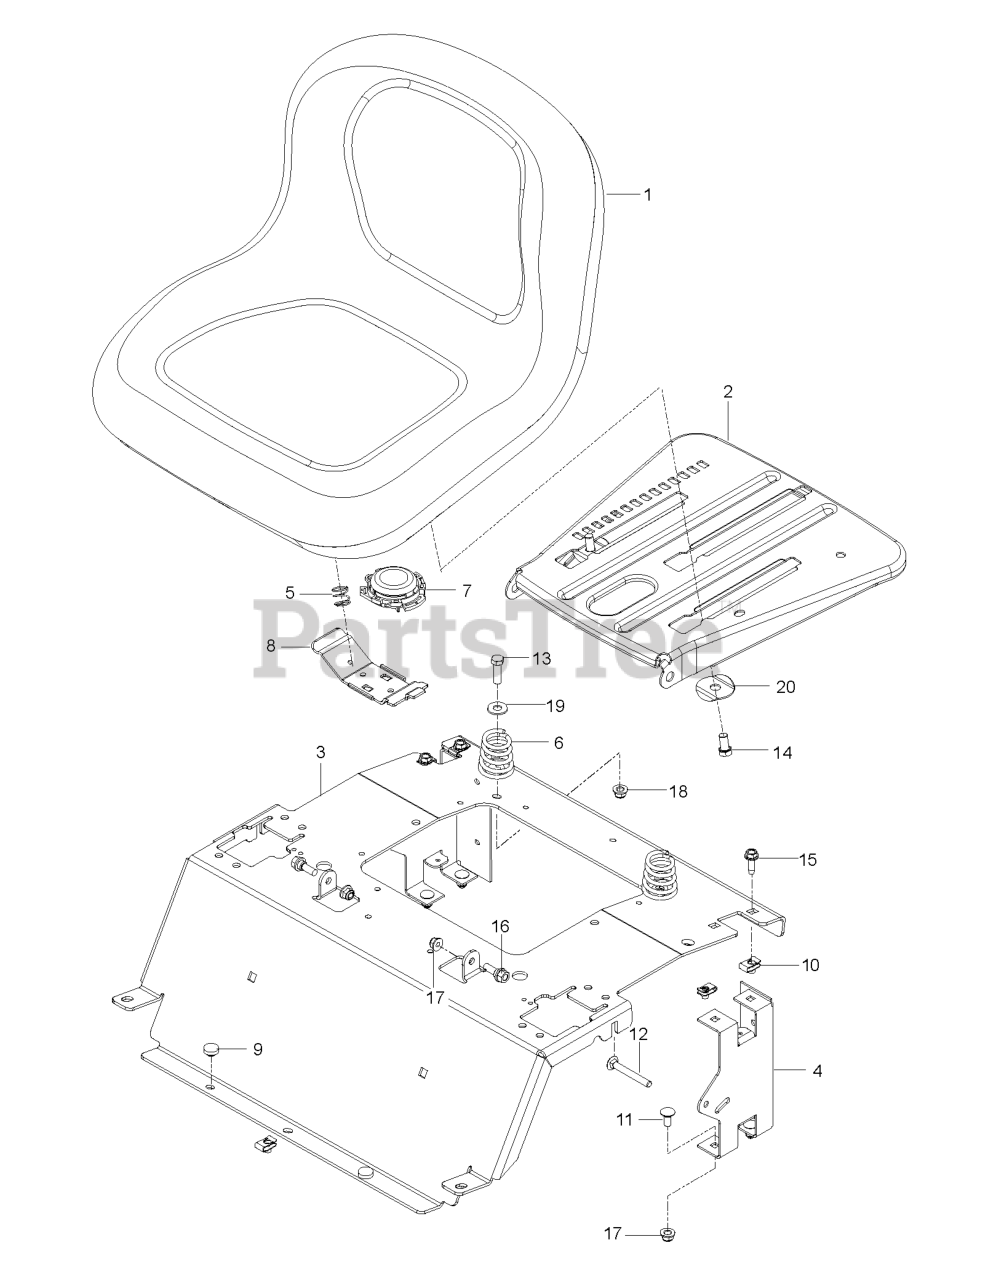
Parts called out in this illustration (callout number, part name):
1	SEAT.TG150.BLK.NLOGO.
2	PLATE.PNT.SEAT.SLIDE.3PT.EDIP
4	SUPPORT REAR SEAT BLACK
5	SPRING.LATCH.SEAT.TEX
6	SPRING.COMPRESS.SEAT.TAPERED
7	SWITCH, SEAT N/C
8	HANDLE.SLIDE.SEAT.TEX.BLACK
9	GROMMET, BUMPER
10	U-CLIP 5/16-18 NUT RETAINER
11	Bolt, Carriage 5/16-18 x 3/4 Gr. 5
12	RHSNB 5/16-18 X 2-1/2 GR5 ZD
13	Bolt Fin Hex 3/8 - 16 UNC x 1-1/4 (AYP part number)
14	Screw, Hex Wsh. Thrdrol. 3/8-16 x 3/4 (AYP part number)
15	Screw, Hex Washer Head, Threaded, Rolling 5/16-18 x 3/4 Type TT
16	BOLT, SHOULDER
17	5/16-18 NYLOC FLANGE NUT
18	NUT 3/8-16 HEX FLG NYLOC ZD
19	WASHER 3/8 FLAT
20	WASHER.WINGED.3/8ID.1.5OD
